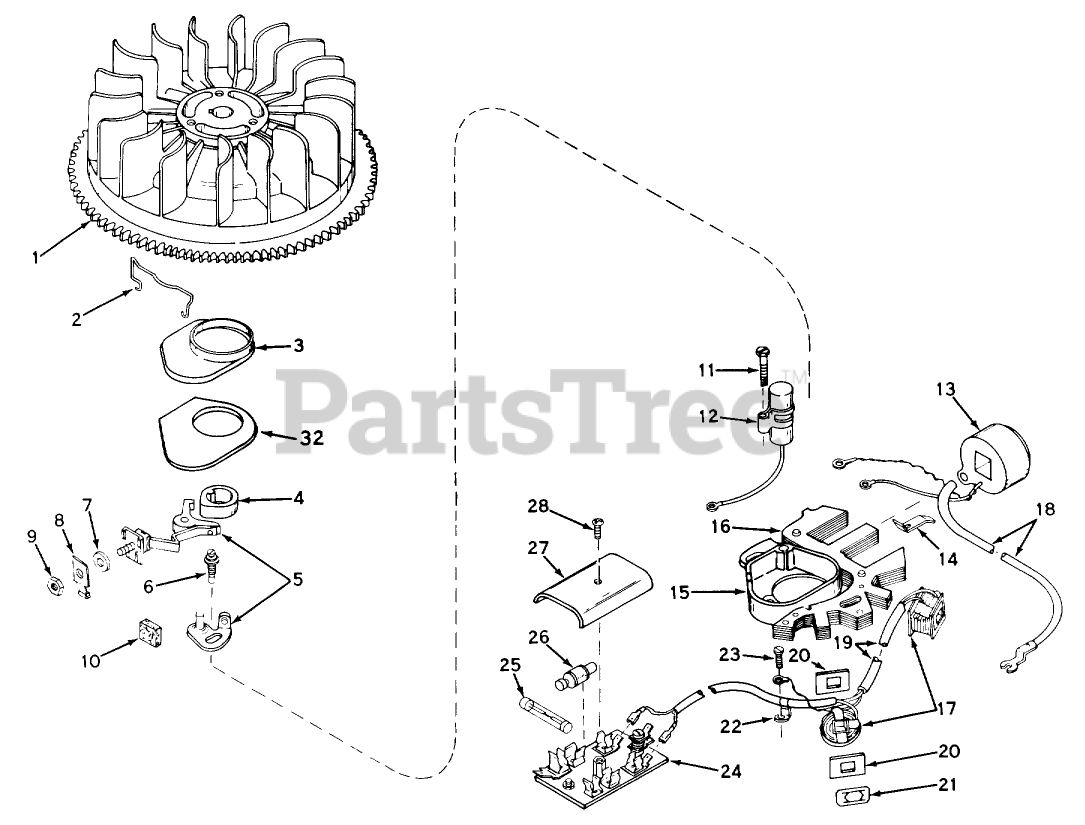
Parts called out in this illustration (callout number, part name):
1	Flywheel
2	Spring, Dust cover
3	Cover, Dust
4	Cam-Breaker
5	Breaker Assy.
6	Breaker Screw
8	Terminal
10	Felt,Cam Wiper
11	Condenser Screw
12	Condenser
13	Coil Assy. (Incl. Nos. 12, 14 & 18)
14	Spring Coil Wedge
15	Stator Plate Assy. (Incl. Nos. 2, 3, & 5 thru 28 & 32)
16	CONTOUR PLUS II CUTTING DECK
17	Generator Coils & Leads
18	Wire, Lead
19	Sleeve, Insulation
20	Shield, Coil
21	Clip, Coil fastening
22	Clip, Ground
23	Screw, Ground
24	Plate, Rectifier (Does not incl. 25 & 26)
26	Rectifier
27	Cover, Panel
32	Gasket Dust
